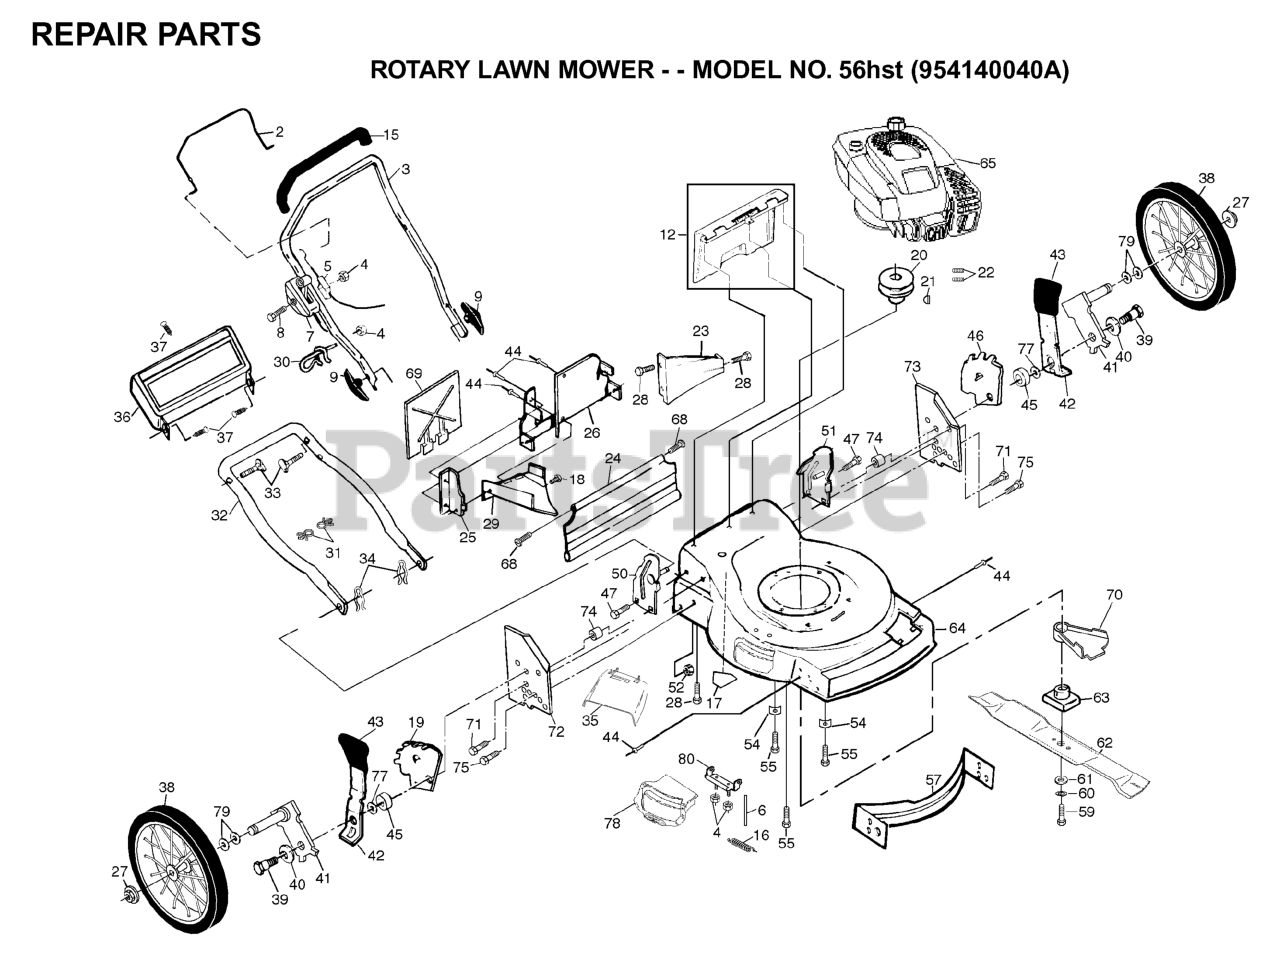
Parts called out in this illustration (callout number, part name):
2	BAIL.CONTROL.WIRE.STD.COMF.BLK
3	UPPER HANDLE
4	NUT
5	CABLE ASSEMBLY
6	ROD.HINGE.COMBI-C
7	THROTTLE CONTROL
8	SCREW 1/4-20 X 2.12
9	HANDLE KNOB
15	HANDLE GRIP
16	SPRING HINGE
17	DECAL HYT
18	SCREW.HXTAP.10-24
19	WHL ADJ BRKT LF/RR
20	ENGINE PULLEY
21	HI PRO KEY PM WSL
23	REAR BAFFLE
24	REAR SKIRT
25	SIDE BAFFLE
27	HEX FLANGE LOCKNT
29	DISCHARGE BAFFLE
30	ROPE GUIDE
31	TIE GUIDE
32	HANDLE, LOWER
33	HANDLE BOLT
34	HAIRPIN COTTER
36	TRIM PLATE
38	WHEEL TIRE PM
39	BOLT
42	SELECTOR SPRING
43	SELECTOR KNOB
44	RIVET BLIND
45	RP SPACER HT ADJ
46	WHL ADJ BRKT RF/LR
47	SELF-TAPPING SCREW 5/16-18X3/4
52	LOCKNUT PM
54	WASHER.ENGINE.BZP
55	BOLT 3/8-16X1-1/8
57	FRONT BAFFLE
59	SCREW, HEX HD 3/8-24 X 1-3/8
60	LOCKWASHER
61	WASHER,HARDEN
63	BLADE ADAPTOR
68	HINGE SCREW
69	MULCHER PLATE
70	DEBRIS SHIELD
77	WASHER.FLAT.1/2
79	WAVE WASHER
80	BRACKET.HINGE ASM.W/FIN
81	CLIP CABLE SNAP
